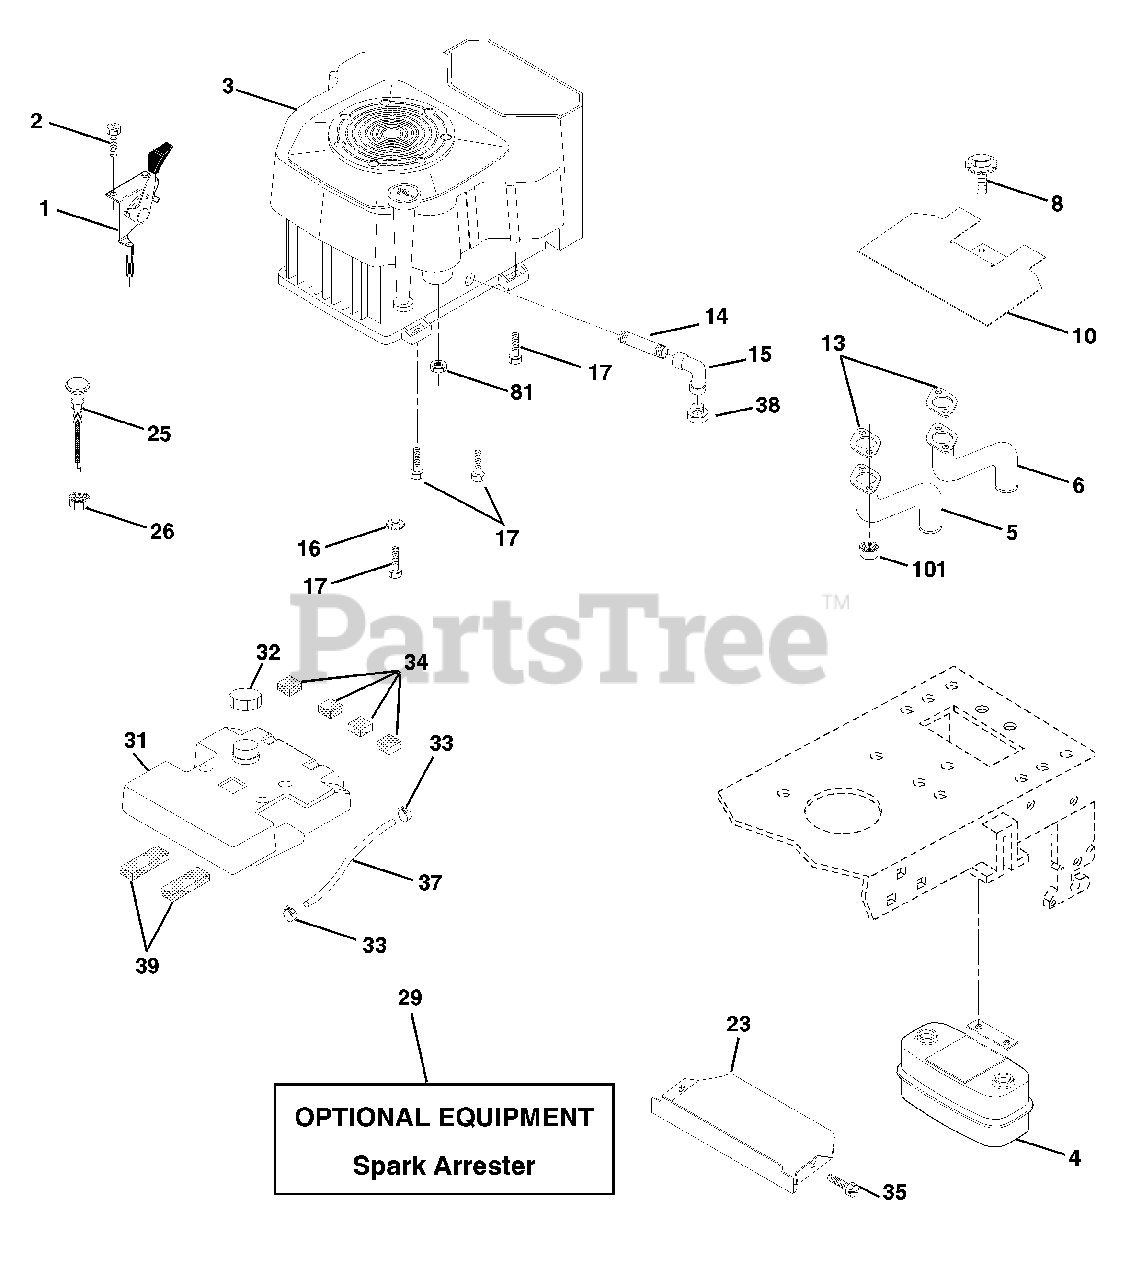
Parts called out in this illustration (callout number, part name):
1	Control Throt Flg 180 LH
2	Screw Hex Thd Cut 1/4-20x5/8 T
4	Muffler Asm Twin Lo-Tone
5	Pipe Exhaust CV18/20 LH
6	Pipe Exhaust CV18/20 RH
8	Bolt 5/16-18unc x 3/4 W/Sems
10	Shield Heat Muffler CV18/20
13	Gasket Kohler CV18-CV26
14	Nipple Pipe 3/8 Npt X 4-1/2"
15	Elbow Std 90 Degree 3/8-18 Npt
16	Washer Lock Ext Tooth 3/8
17	Screw Thdrol 3/8-16 x 1-1/2
23	Shield Browning
25	Choke Control 37"
26	Nut, Keps 3/8-24 Unf
29	Kit Spark Arrestor (Flat Scrn)
31	Tank Fuel 3 50 Rear
32	Cap Asm Fuel Top N/Lany Vented
33	Clamp Hose Blk
34	Pad, Spacer
35	Screw Thdrol 5/16-18 x 3/4
37	Line Fuel 7.5
38	Plug Oil Drain
39	Pad, Idler
81	Nut Flange 1/4-20 Starter Nut
101	Nut Flange M8-1.25 Non-Lk Zinc
